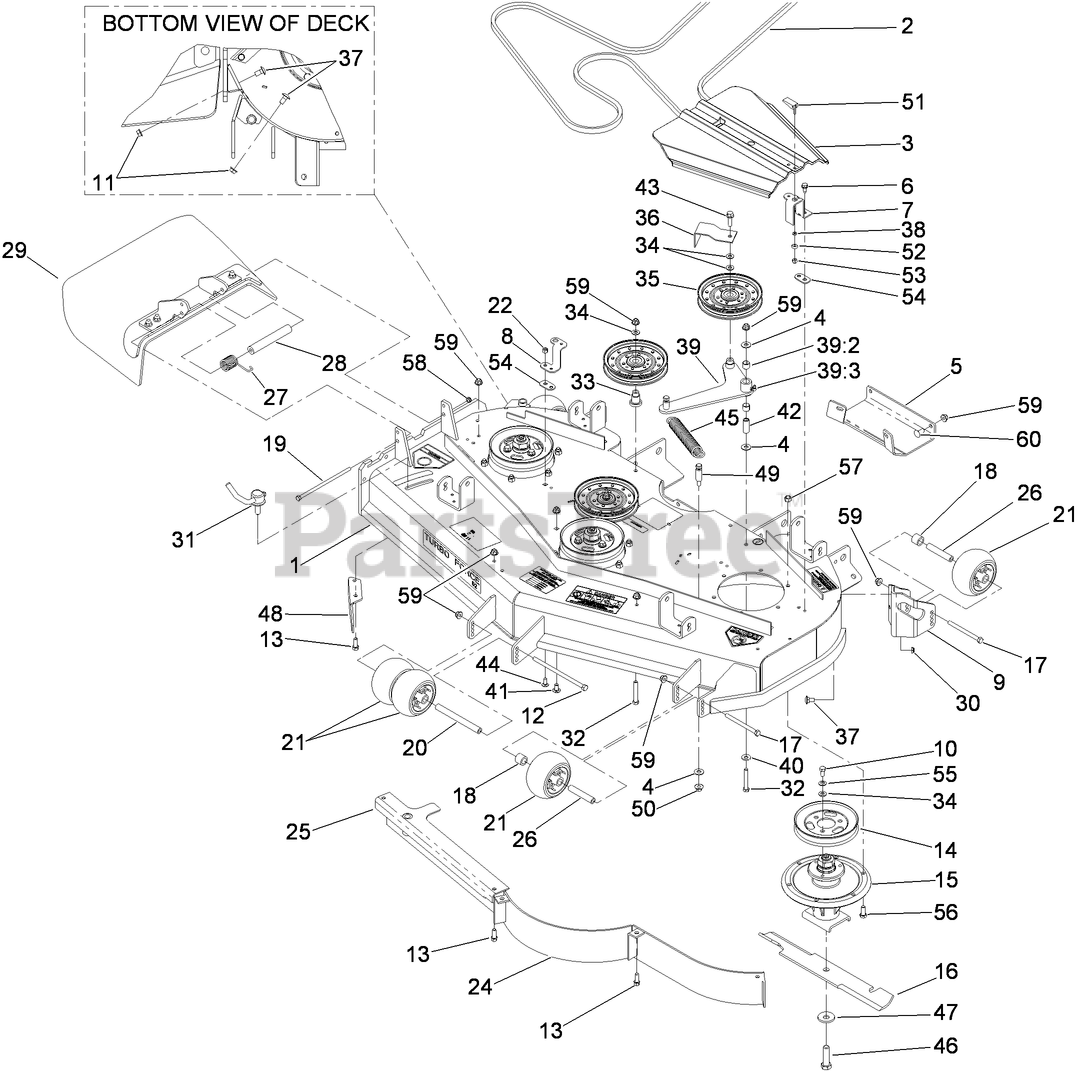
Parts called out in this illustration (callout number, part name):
1	DECK DECAL ASM
2	BELT-V
3	COVER-BELT
4	WASHER-FLAT
5	Plate-Skid
6	SCREW-HWHTF
7	BRACKET-COVER
8	BRACKET-COVER, TALL
9	MOUNT-WHEEL, LH
10	SCREW-HH
11	NUT-HHF, WHIZ
12	SCREW-HH
13	SCREW-HWH
14	Pulley
15	SPINDLE ASM
16	BLADE-18IN, HI FLOW
17	SCREW-HH
18	TUBE-SPACER
19	SCREW-HH
20	SPACER-WHEEL
21	ROLLER-SCALP, ANTI
22	NUT-LOCK, NI
26	TUBE-SPANNER
27	SPRING-TORSION
28	SPACER
29	RUBBER DEFLECTOR ASM
30	NUT-LOCK, NI
31	LEVER ASM
32	SCREW-HH
33	MOUNT-PULLEY
34	WASHER-FLAT
35	Idler-Flat
36	GUIDE-BELT
37	SCREW-CARR
38	WASHER
39	DECK IDLER ARM ASM
39:2	SLEEVE-BEARING
39:3	FITTING-GREASE, 90 DEG
40	WASHER-BELLEVILLE
41	SCREW-CARR
42	BUSHING
43	SCREW-HHF
44	SCREW-CARR
45	SPRING-EXTENSION
46	SCREW-BLADE
47	Washer-Blade Bolt, Heavy
48	BAFFLE-DISCHARGE
49	PIN-THREADED, SPRING ANCHOR
50	NUT-HF
51	HANDLE-LATCH, SWELL
52	BUSHING-LATCH, SWELL
53	NUT-LOCK, HH
54	SPACER-BELT COVER
55	WASHER-BELLEVILLE
56	SCREW-HH
57	NUT-LOCK, NI
58	NUT-LOCK, NI
59	NUT-HF, NI
60	SCREW-CARR
